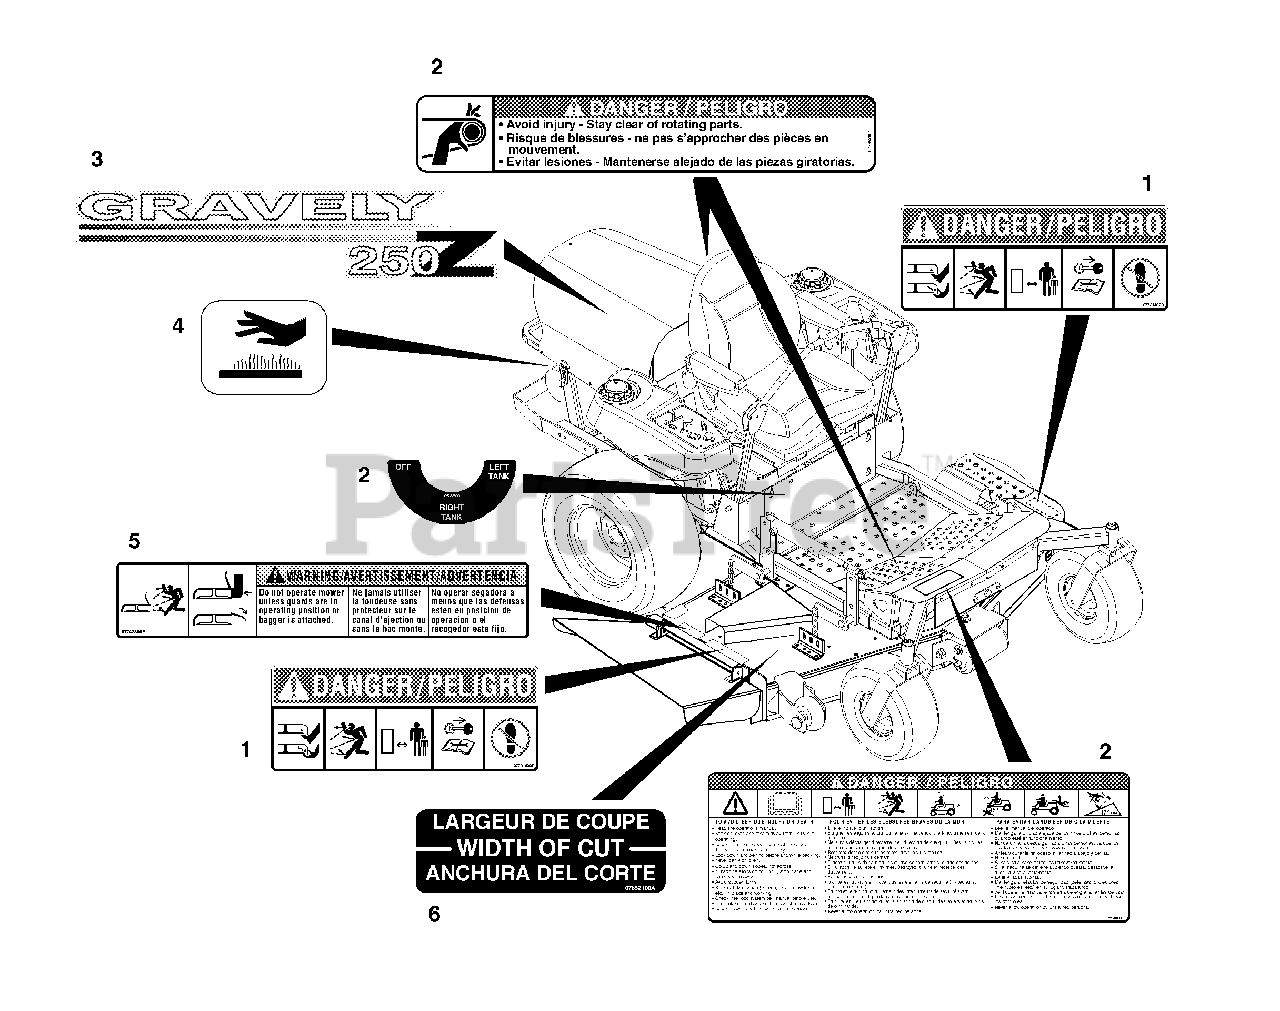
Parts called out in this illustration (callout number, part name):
1	Decal, Mower Pan Head Danger
2	Set, Decal-Common Danger/Fuel
3	Decal, PM-250Z Hood
3	Decal, PM-260Z Hood
3	Decal, PM-272Z Hood
4	Decal-Hot Surface
5	Decal, Warning
6	Decal, Width of Cut
